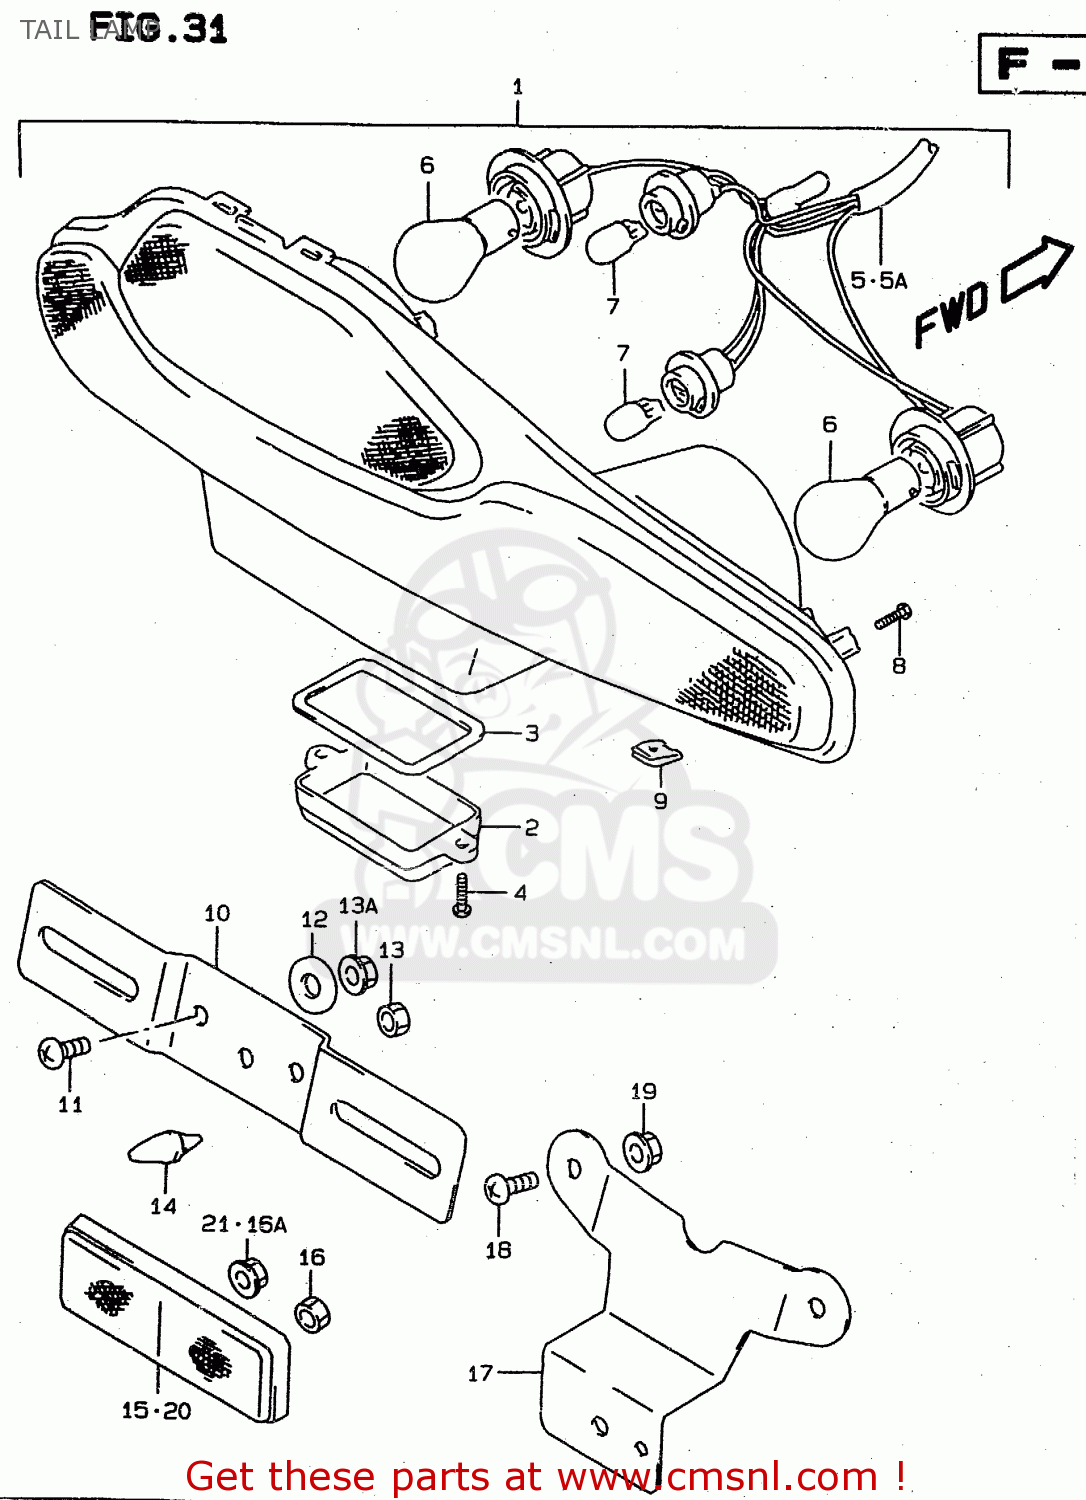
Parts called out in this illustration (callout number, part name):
1	LAMP ASSY,RR COMBINATION
2	LENS,LICENSE LAMP
3	GASKET (NAS)
4	SCREW
5	SOCKET ASSEMBLY
5A	SOCKET & CORD
6	BULB(12V21W)
7	BULB(12V5W)
8	TPG SCREW
9	NUT
10	BRACKET, LICENSE PLATE
11	SCREW 6X12
12	WASHER(6.5X20X1.6)
13	NUT 6MM
13A	NUT
14	CUSHION
15	REFLECTOR ASSY,RR
16	NUT
16A	NUT
17	BRACKET,RR REFLECTOR
18	SCREW 6X12
19	NUT
20	REFLEX REFLECTOR,FR SIDE
21	NUT
